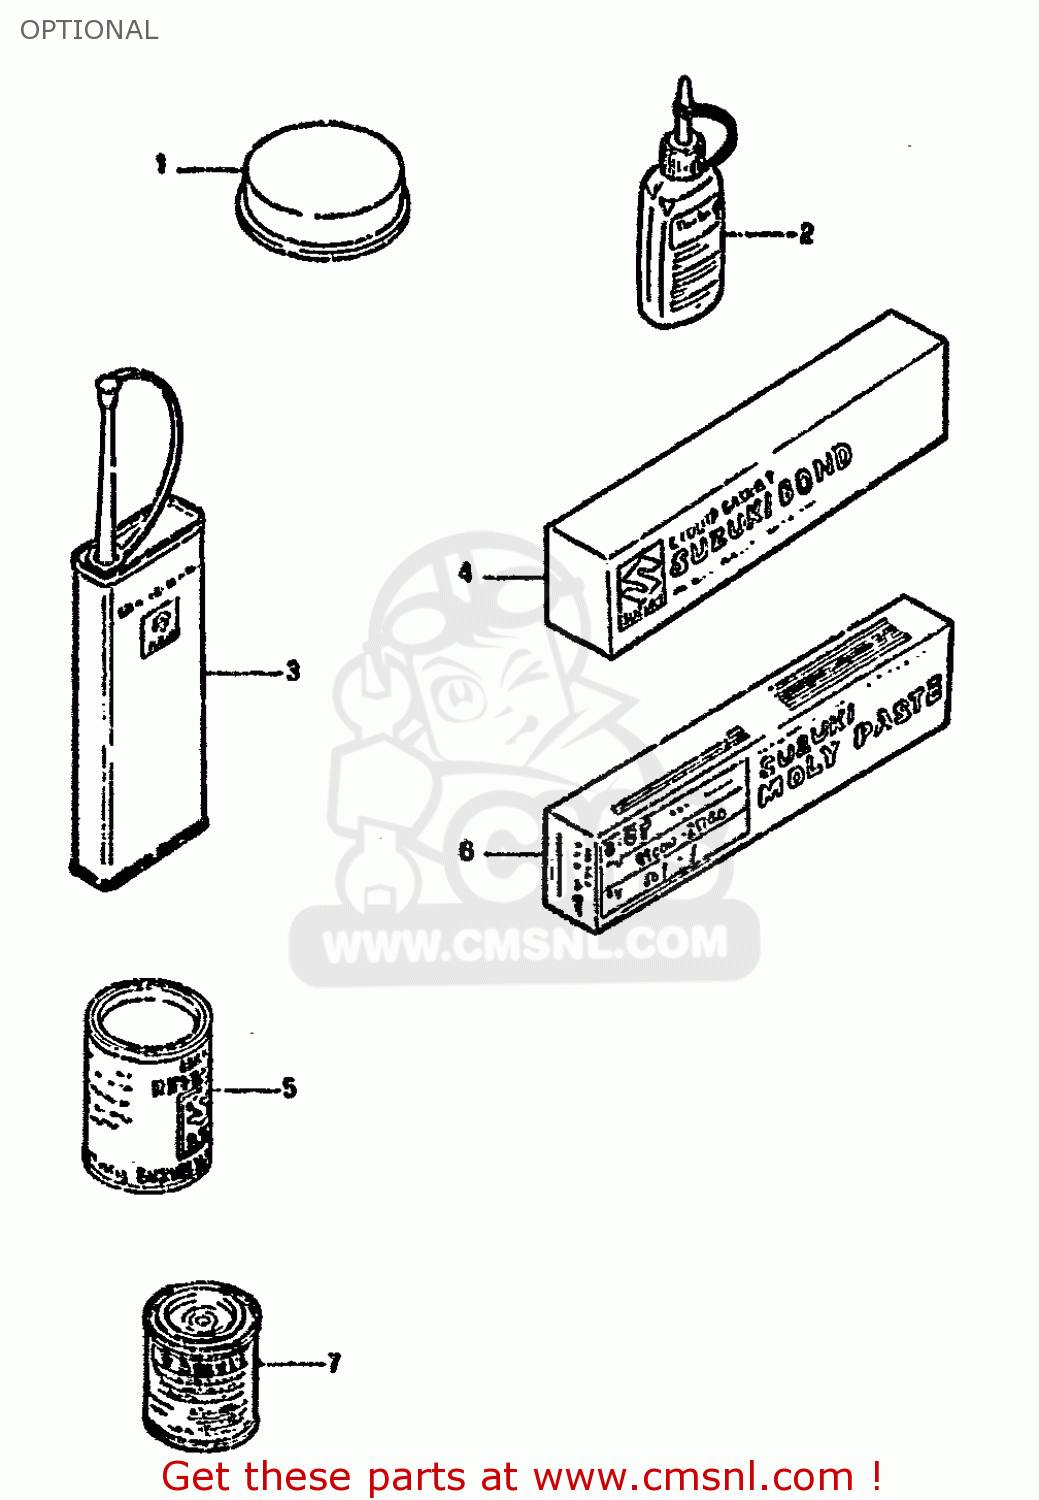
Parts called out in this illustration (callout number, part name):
1	GREASE,PBC FOR BRK PAD 20G
2	THREAD LOCK NO.1342
3	THREAD LOCK NO.1401 CLEAR 200G
4	LIQUID GSKT NO.1215 250G
5	GREASE(C)EP2 LITHIUM 150G
6	SUZUKI MOLY PASTE
7	PAINT,BLACK
